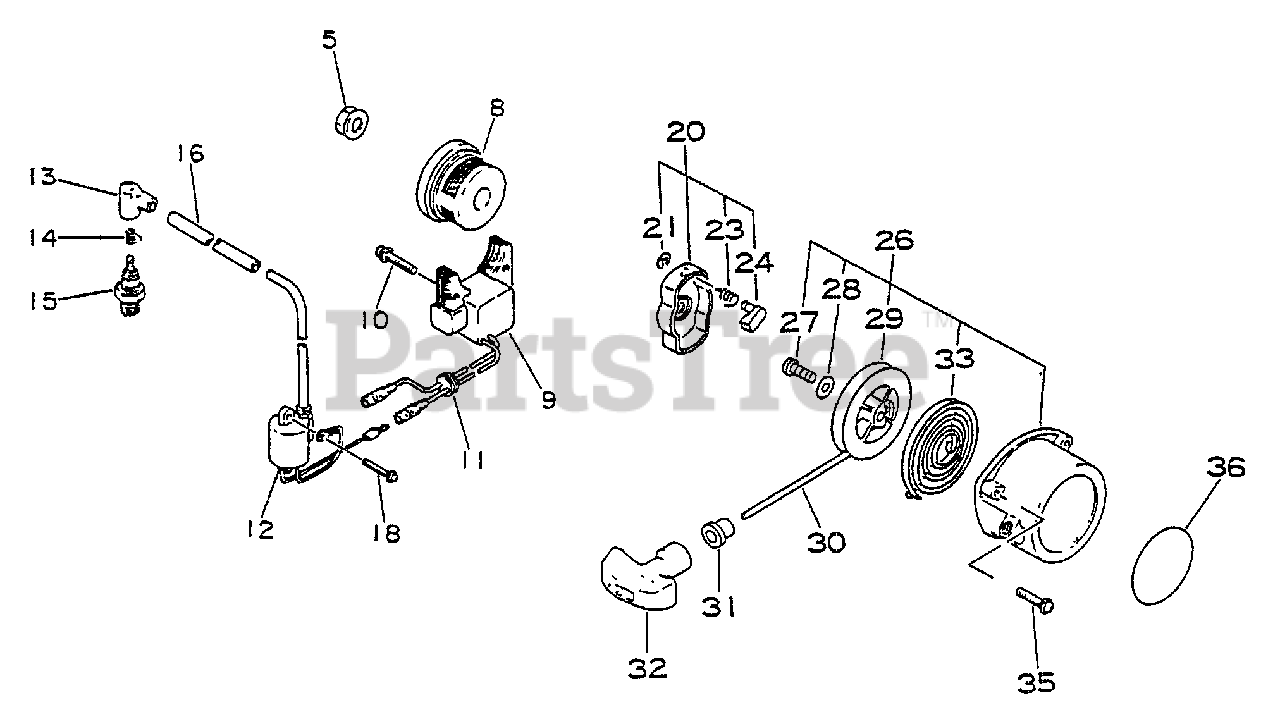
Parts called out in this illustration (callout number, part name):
5	NUT - 10 -- FLANGE
8	FLYWHEEL
9	COIL, IGNITION
10	SCREW - 5X25
12	COIL, IGNITION
13	CAP, SPARK PLUG
14	TERMINAL, SPARK PLUG CAP
15	SPARK PLUG -- BM-6A
18	SCREW - 4X25
20	STARTER PAWL ASSY
21	RING, RETAINING - 4
23	SPRING, RETURN
24	PAWL, STARTER
26	STARTER ASSY
29	REEL, ROPE
30	ROPE, STARTER - 4X880
31	GUIDE, ROPE
32	GRIP, STARTER
33	SPRING, REWIND
35	SCREW - 5X16
36	LABEL - ECHO
